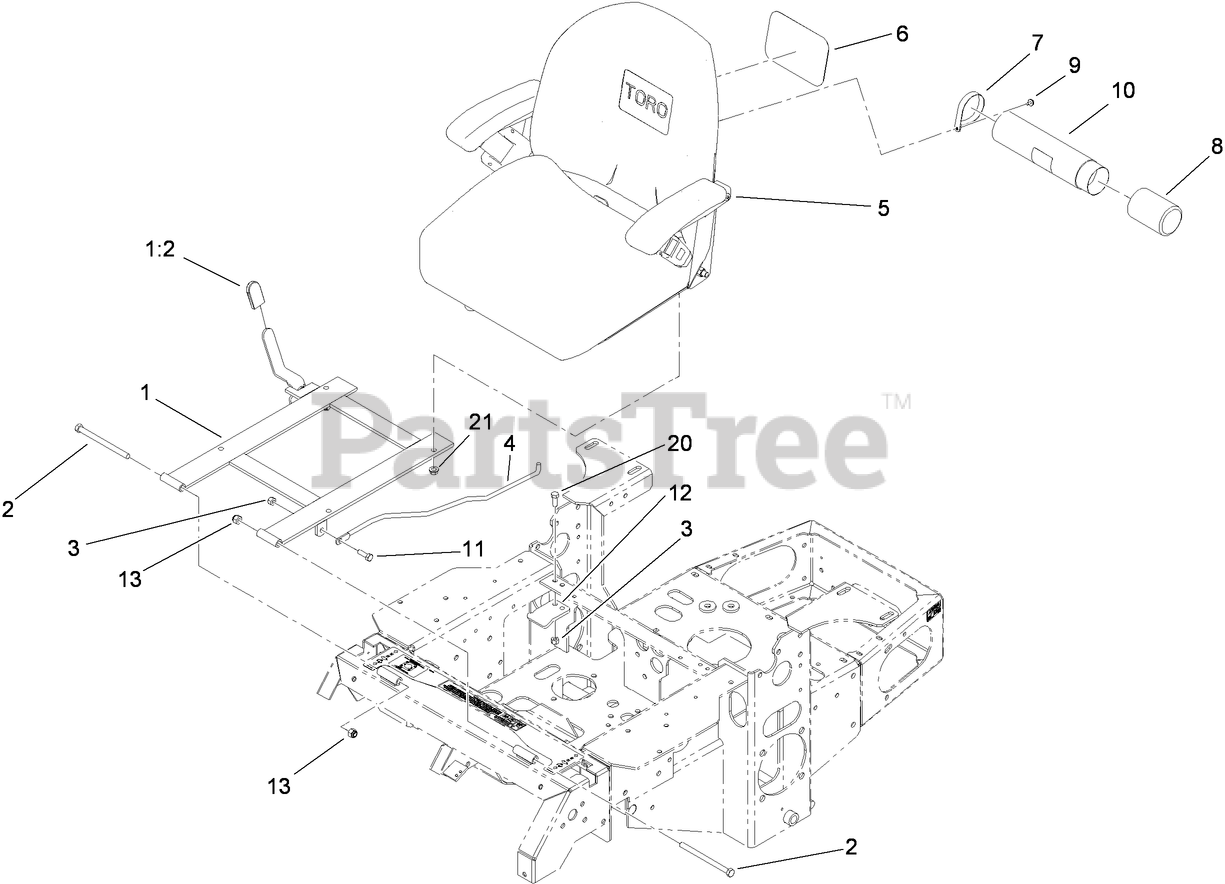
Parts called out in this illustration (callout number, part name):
1	SEAT FRAME AND LATCH ASM
1:2	GRIP-LEVER
2	SCREW-HH
3	NUT-LOCK, NI
4	ROD-RETAINER, SEAT
5	SEAT ASM
6	DECAL
7	CLAMP-R
8	CAP-HOUSING
9	SCREW-HWHTF
10	TUBE-MANUAL
11	SCREW-HH
12	CATCH-LATCH, SEAT
13	NUT-LOCK, NI
20	SCREW-HH
21	NUT-HF
